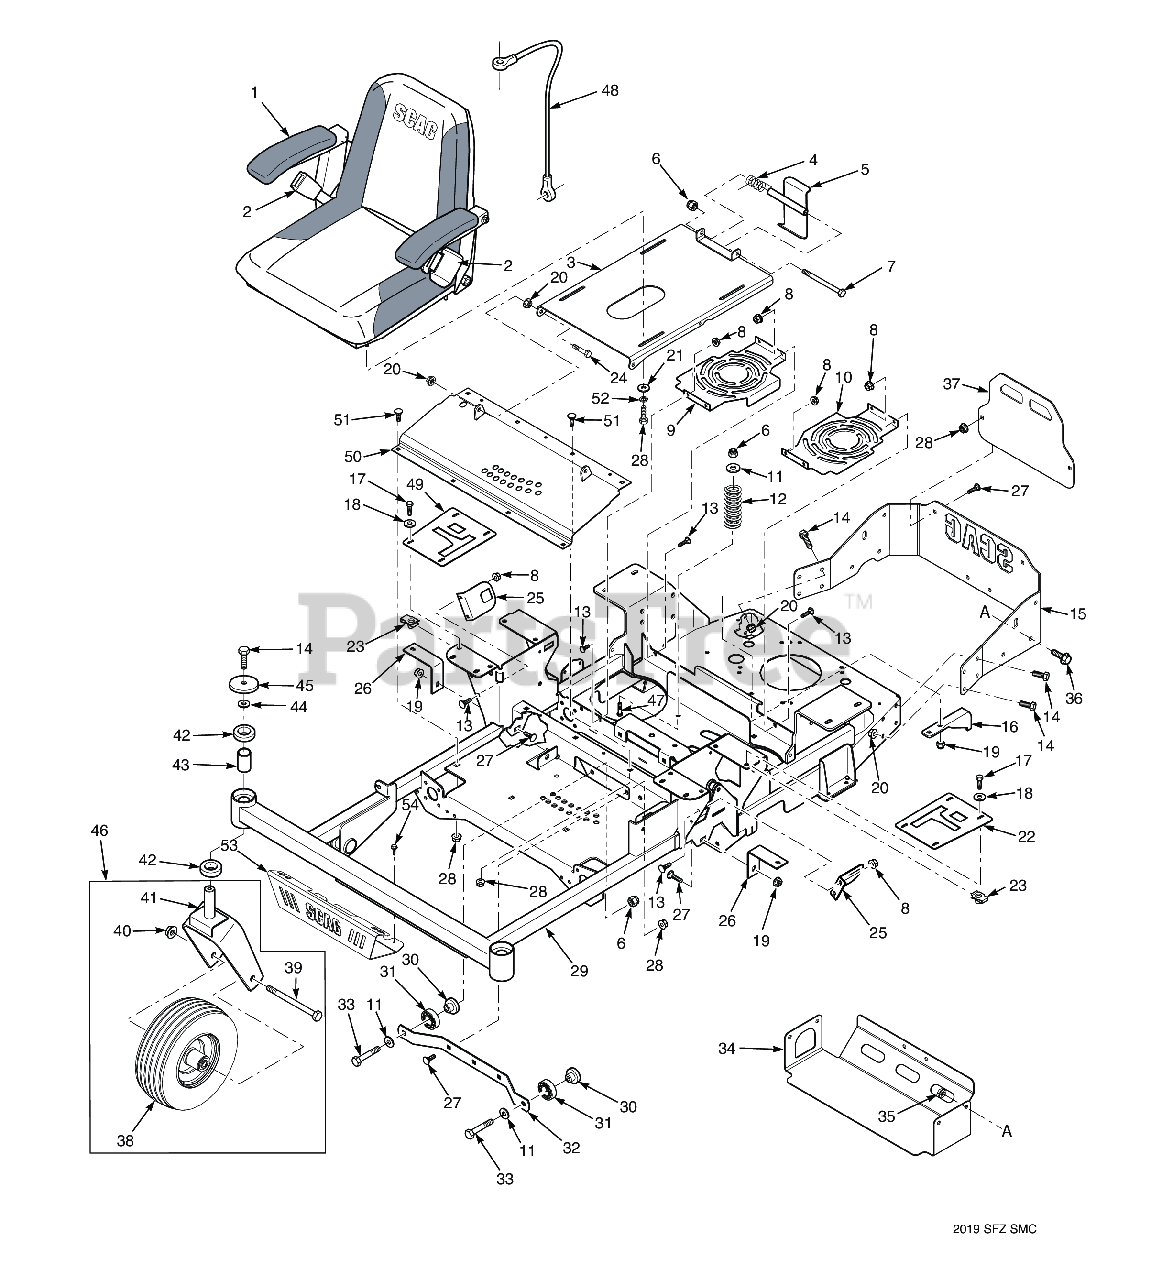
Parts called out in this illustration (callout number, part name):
1	Seat Assembly
1	Back Cushion
1	Cover, Bottom Cushion
1	Arm Rest Kit
1	Seat Pan
2	Seat Belt Assembly, Retractable
2	Hardware Package, Seat Belt Mounting
3	Seat Base w/Decal
4	Spring, Seat Latch
5	Weldment, Seat Latch
6	HEX NUT, ELASTIC STOP LOCK, 3/8-16
7	Bolt, 3/8-16 x 6.00" Hex Head
8	NUT, 1/4-20 SERRATED FLANGE HEX HEAD
9	Fan Cover, RH
10	Fan Cover, LH
11	Flatwasher, 3/8" Special (.391 x .938 x .105)
12	Spring, Seat
13	Bolt, Carriage 1/4-20 x 1/2"
14	Bolt, Hex Head, 3/8-16 x 1 Gr. 5
15	Rear Bumper
16	Bracket, Anti-Rotation
17	Capscrew, Hex Head 1/4-20 x 1"
18	Flatwasher, 1/4" (.312 x .750 x .065")
19	HEX NUT, ELASTIC STOP LOCK, 5/16-18
20	NUT, 3/8-16 SERRATED FLANGE HEX HEAD
21	Flatwasher, 5/16-.375 x .875 x .083 (35BV & 37BV-EFI)
22	Control Plate LH
23	Bolt, Hex Head 3/8-16 x 1"
24	Bolt, Hex Head, 3/8-16 x 1-1/2"
25	Bracket, Switch Mount
26	Bracket, Tank Mount
27	Bolt, 5/16-18 x .75 RHSN Carriage
28	BOLT, SERRATED FLANGE HEX HEAD 5/16-18 X 3/4"
29	Main Frame w/Decals
30	Spacer, Bearing
31	Bearing
32	Support, Deck Guide
33	Bolt, Hex Head 3/8-16 x 1-3/4" (Kohler EFI)
34	Heatshield
35	NUT, 3/8-16 SERRATED FLANGE HEX HEAD
36	Bolt, Hex Head Serrated Flange 3/8-16 x 3/4"
37	Engine Guard
38	Caster Wheel Assembly (INCL. Rim - 486311)
38	TIRE, 11 X 6.00-5
39	Bolt, Hex Head 1/2-13 x 7-1/2" (48"/52")
40	HEX LOCKNUT, ELASTIC STOP, 1/2-13
41	Yoke, Caster Wheel
42	Bearing
42	Spacer, Yoke
43	Spacer, Caster Bearing
44	Flatwasher, 7/16" (.500 x 1.25 x .083")
45	Flatwasher, 3/8-.406 x 2.25" x .1875
46	CASTER WHEEL & SUPPORT ASSY
47	SHORT SQ. NECK CARRIAGE BOLT, 3/8-16 X 1-1/4"
48	Cable, Seat Stop
49	Control Plate RH
50	Weldment, Deck Lift Cover w/Decal
51	Carriage Bolt, 5/16-18 x 1/2"
52	Lockwasher, 5/16 (.317 x .586 x .078) Helical Spring
53	Bumper. Front
54	Screw, 1/4-20 x .375"
